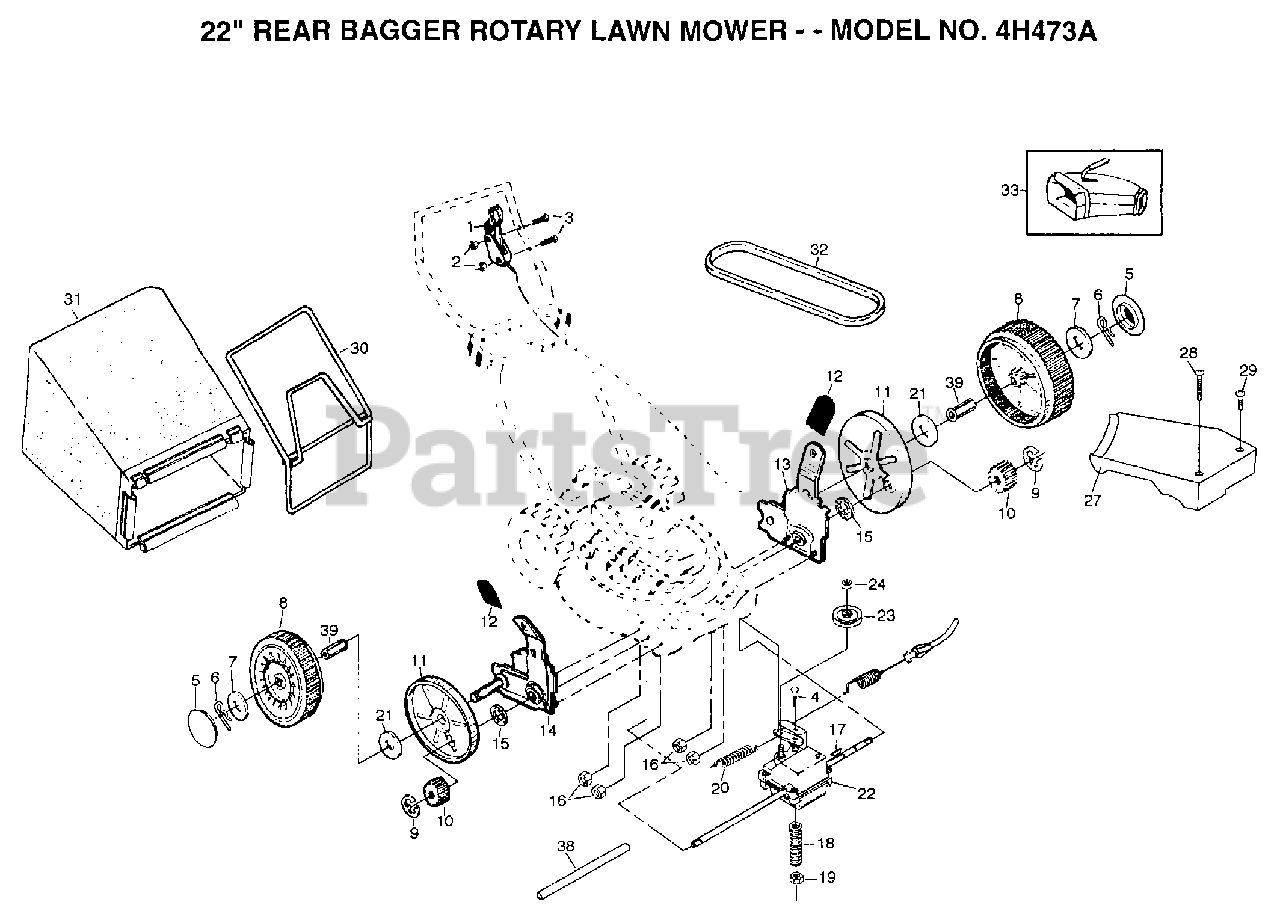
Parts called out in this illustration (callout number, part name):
1	CONTROL.DRIVE
3	SCREW
4	BOLT.1/4-20X2.0
5	HUB CAP
6	RETAINER CLIP PM
7	WASHER
8	WHEEL.8X2.IGD.
10	PINION.GEAR
11	DUST SHROUD PM
12	KNOB PM
15	WASHER PM
17	HI PRO KEY
18	SPRING.RETURN
20	SPRING.TENSION
21	WASHER FLUT
23	PULLEY.DRIVEN
24	LOCKNUT
27	"COVER.DRIVE 22""RD"
30	CATCHER FRAME
31	GRASS BAG
38	DRV SHAFT TUBE PM
39	BUSHING.HEX
